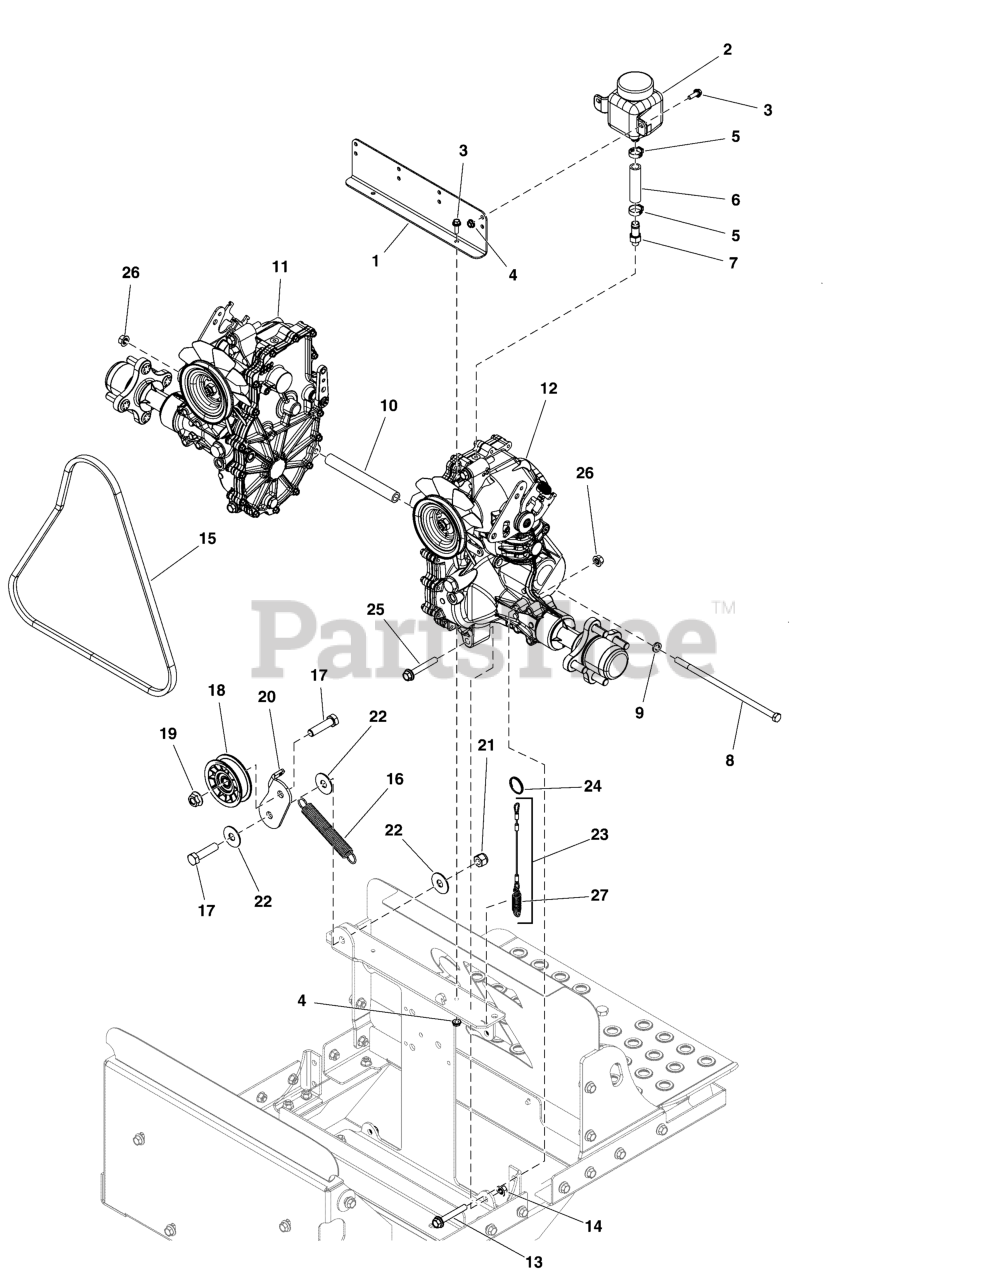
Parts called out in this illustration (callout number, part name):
1	MOUNT, TANK
2	RESERVOIR
5	CLAMP - HOSE
11	TRANSAXLE, ZT3100, RH, ZJ-LPRP-3A7C-19XX
11	TRANSAXLE
12	TRANSAXLE, ZT3100, LH, ZJ-HPRP-3A7B-19XX
12	TRANSAXLE
13	BOLT, HEX, 3/8-16 X 3", SER FLG GRD5, CZ
15	BELT, DRIVE
17	BOLT, 1/2-13 X 2 GD5
18	PULLEY, IDLER
20	ARM, IDLER
23	CABLE, Hydraulic Control
26	NUT, 3/8-16 HEX NYLOCK
27	SPRING, EXTENSION
